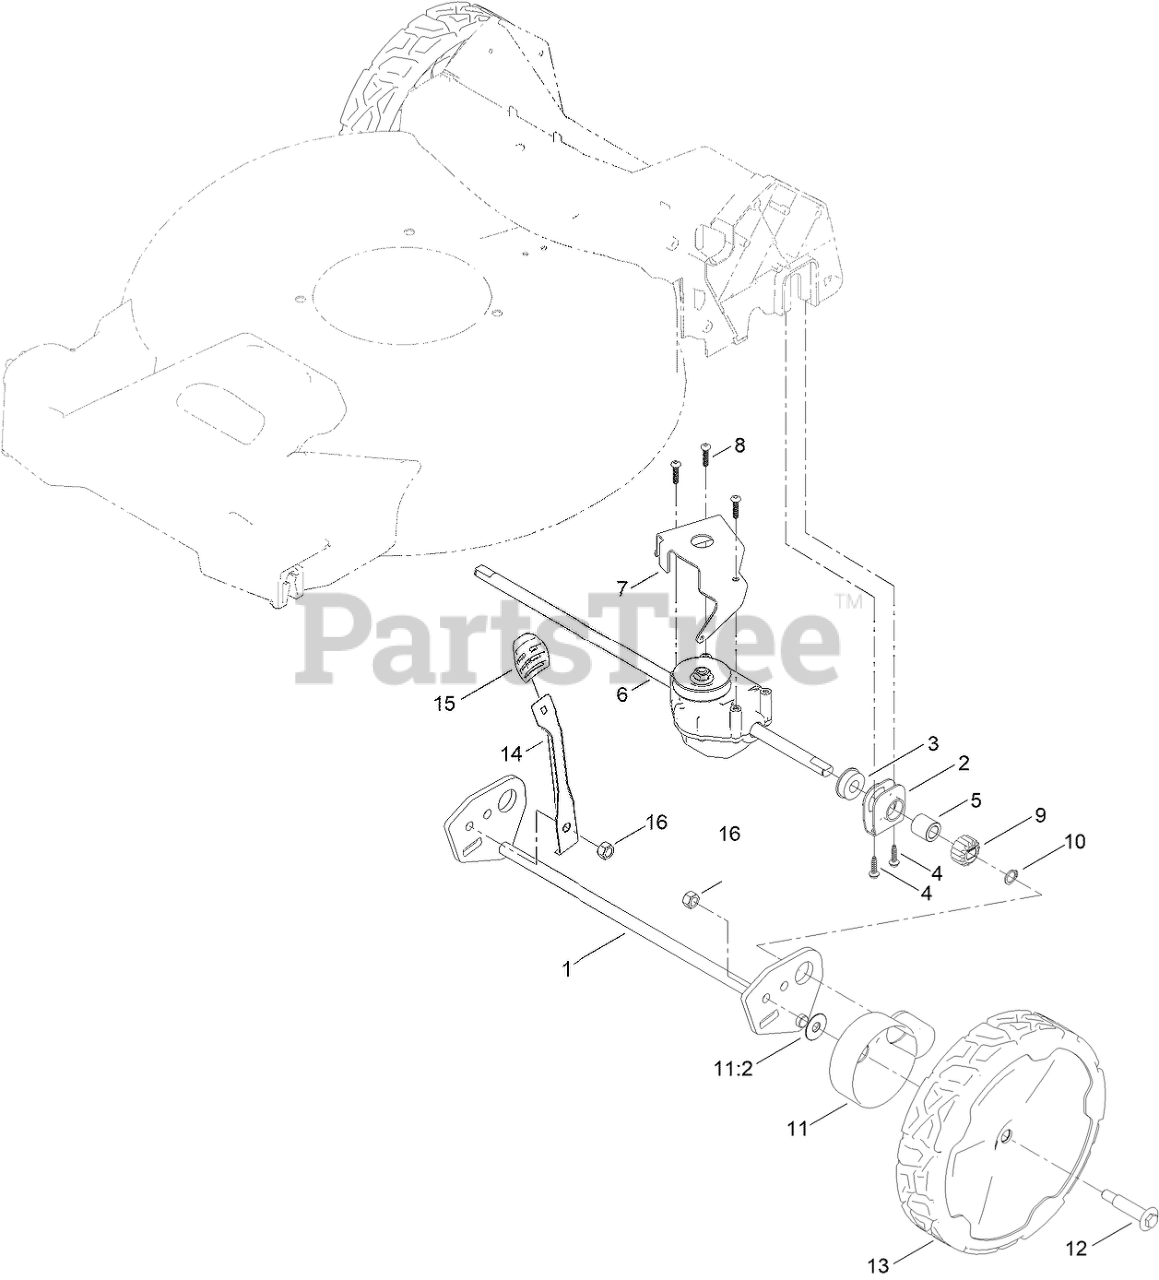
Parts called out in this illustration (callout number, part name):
1	AXLE-REAR, WA
2	RETAINER-BEARING
3	BEARING-BALL
4	SCREW-PLASTIC, HWH
5	BUSHING-SLEEVE
6	TRANSMISSION (7:1 RATIO)
7	BRACKET-TRANSMISSION
8	SCREW-PLASTITE
9	GEAR-PINION, 15T
10	RING-RETAINING
11	ASM-COVER, GEAR (DK GRAY)
11:2	WASHER-STEPPED
12	BOLT-SHOULDER
13	ASM-9.65" WHEEL, GEARED
14	ARM-SPRING
15	KNOB-LEVER, HOC
16	LOCKNUT
